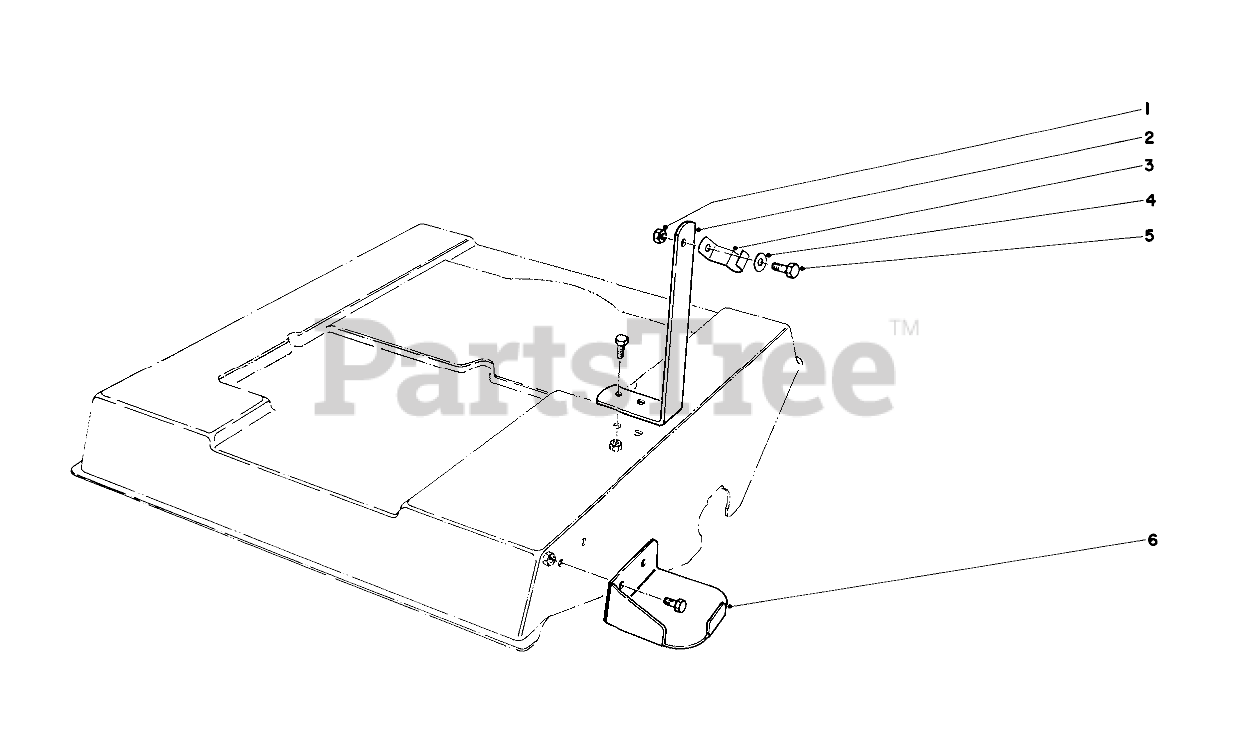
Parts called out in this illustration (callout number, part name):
1	Nut
2	Support, Trimmer Clip
3	Clip Trimmer
4	WASHER-FLAT
5	SCREW-HH
6	Support, Trimmer
